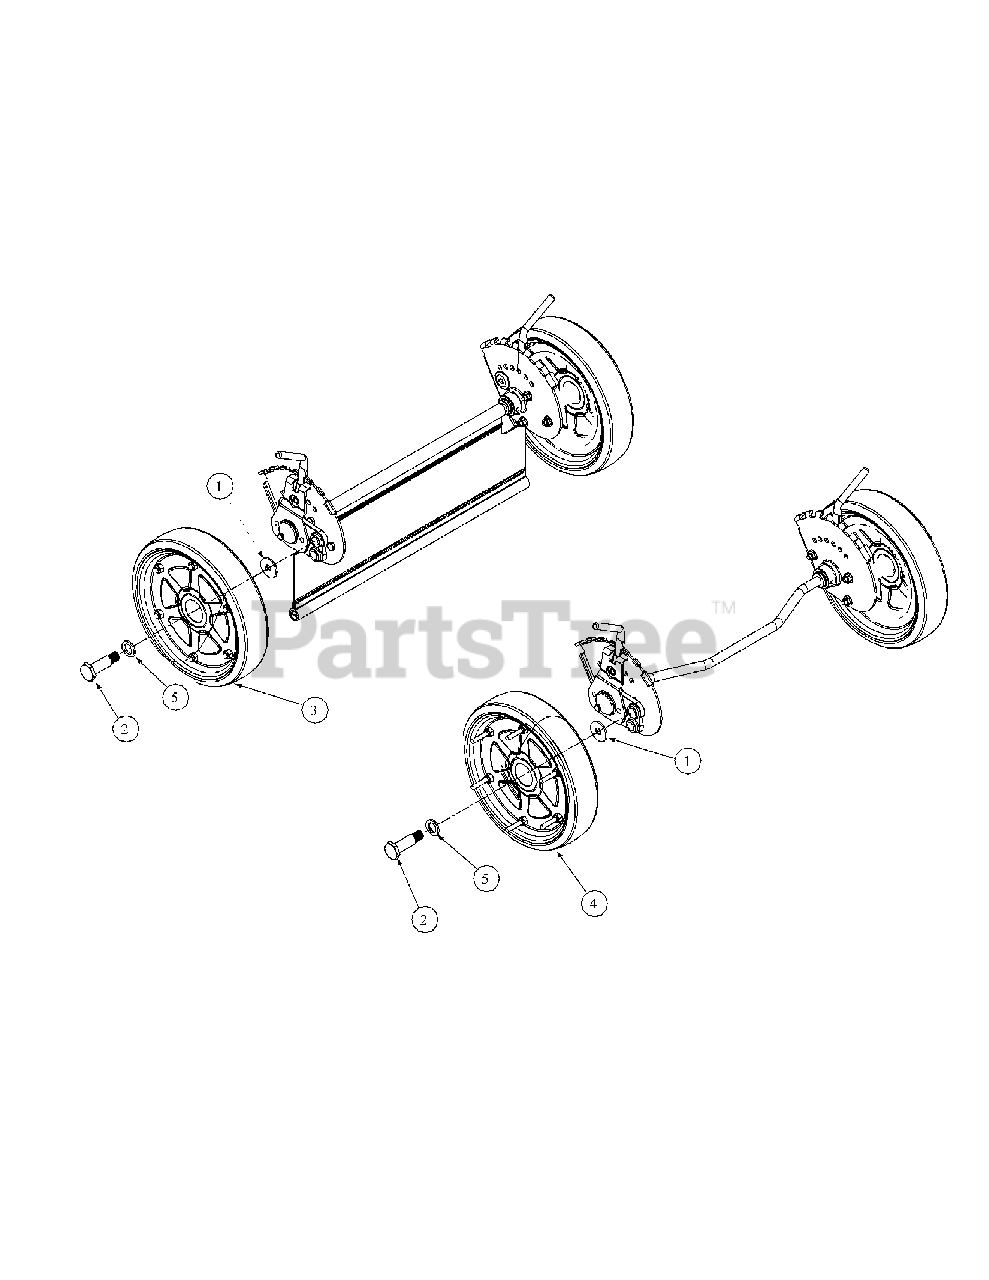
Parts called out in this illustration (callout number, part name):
1	Shim Washer, 1/2 x 3/4 x .031
2	Shoulder Screw, 58 x 1.48, 1/2-20
3	Wheel, 9 x 2 .125 With Drive Gear
4	Wheel, 9 x 2 .125 With Drive Gear
5	Washer, Shim, .625 x .875 x .031
